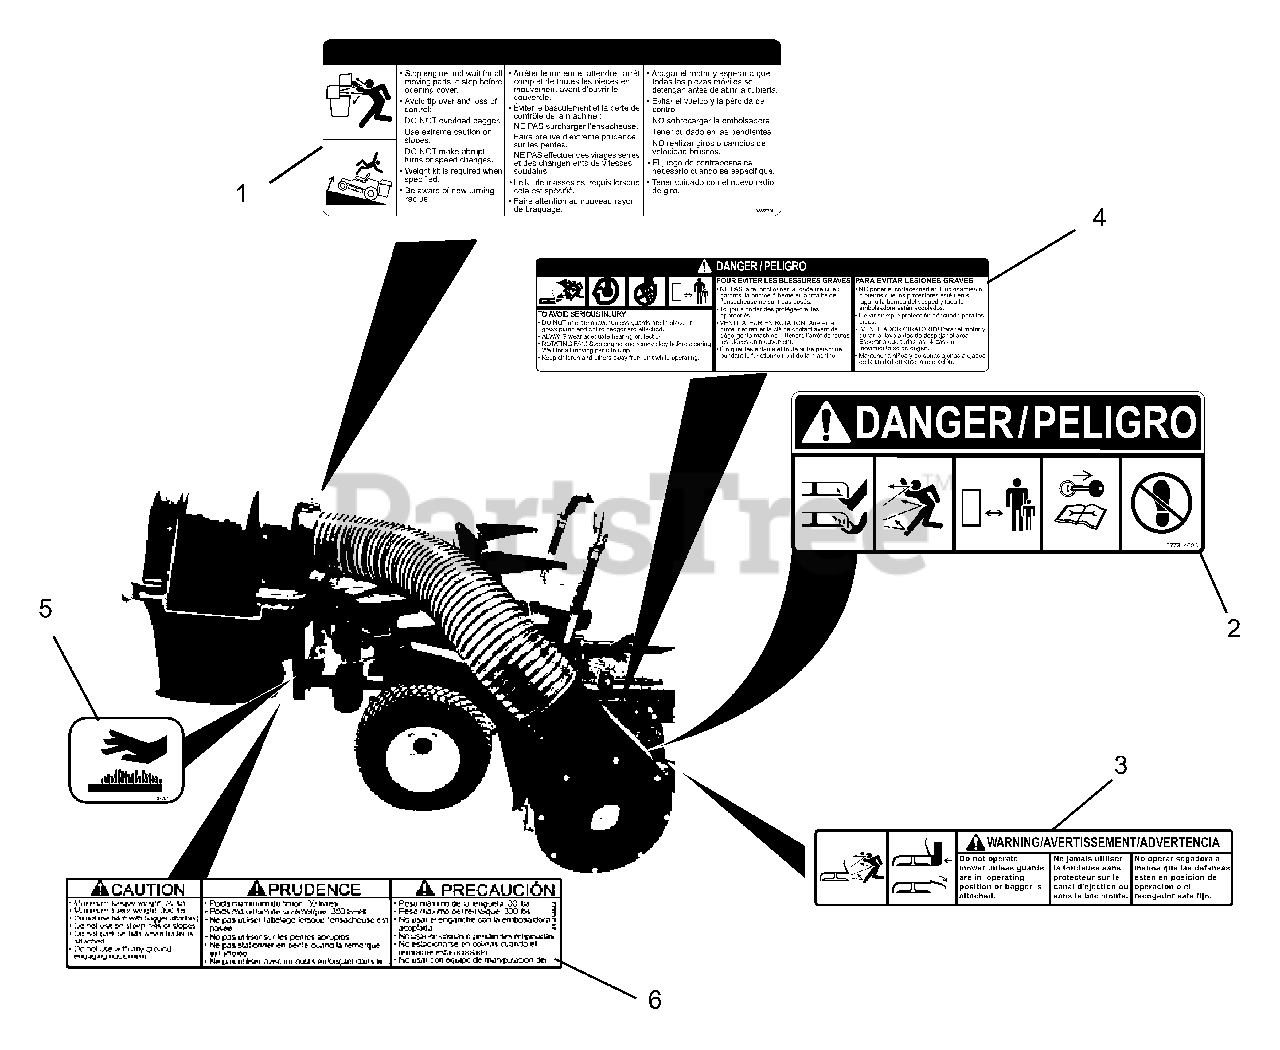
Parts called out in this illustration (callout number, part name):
1	DECAL, BAGGER COVER
2	DECAL, MOWER PAN DANGER
3	DECAL, WARNING
4	DECAL-CAUTION, GRASS PUMP
5	DECAL, HOT SURFACE
6	WHEEL & TIRE, 20X10X8
